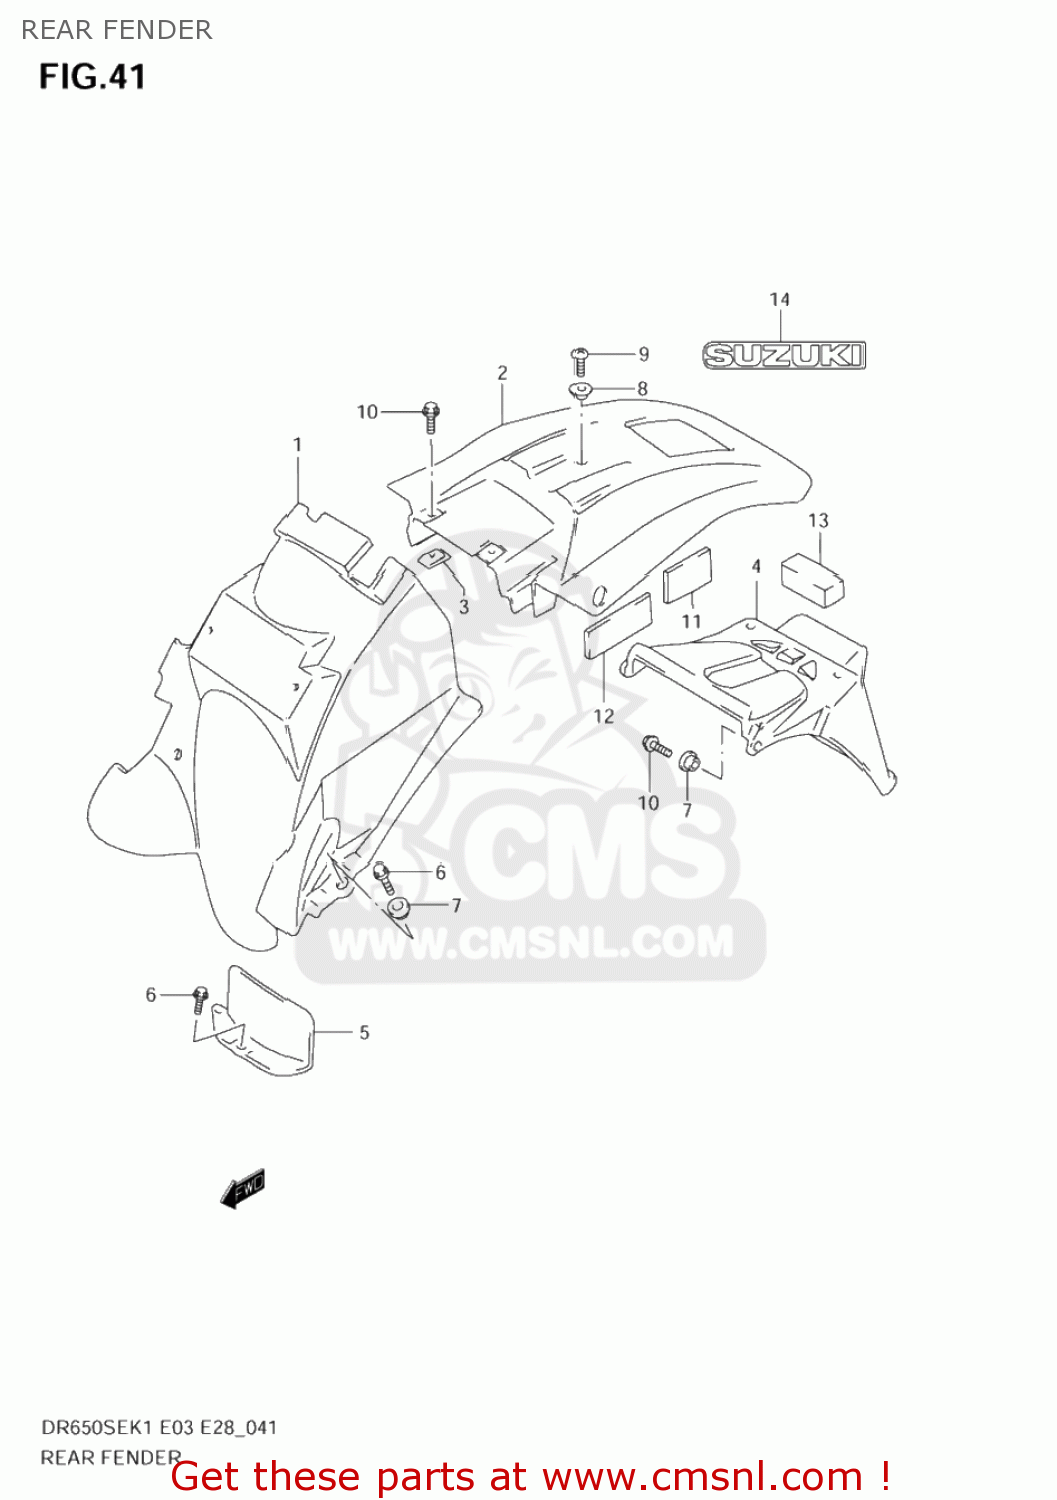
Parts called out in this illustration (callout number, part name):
1	BODY,RR FENDER FR
2	BODY,RR FENDER RR
3	PLATE,FRAME COVER
4	EXTENSION,RR FENDER
5	MUDGUARD,RR FENDER
6	BOLT(6X16)
7	WASHER
8	WASHER
9	SCREW(6X16)
10	BOLT
11	CUSHION
12	CUSHION,RR FENDER
13	CUSHION,EXTENSION
14	EMBLEM,SUZUKI
